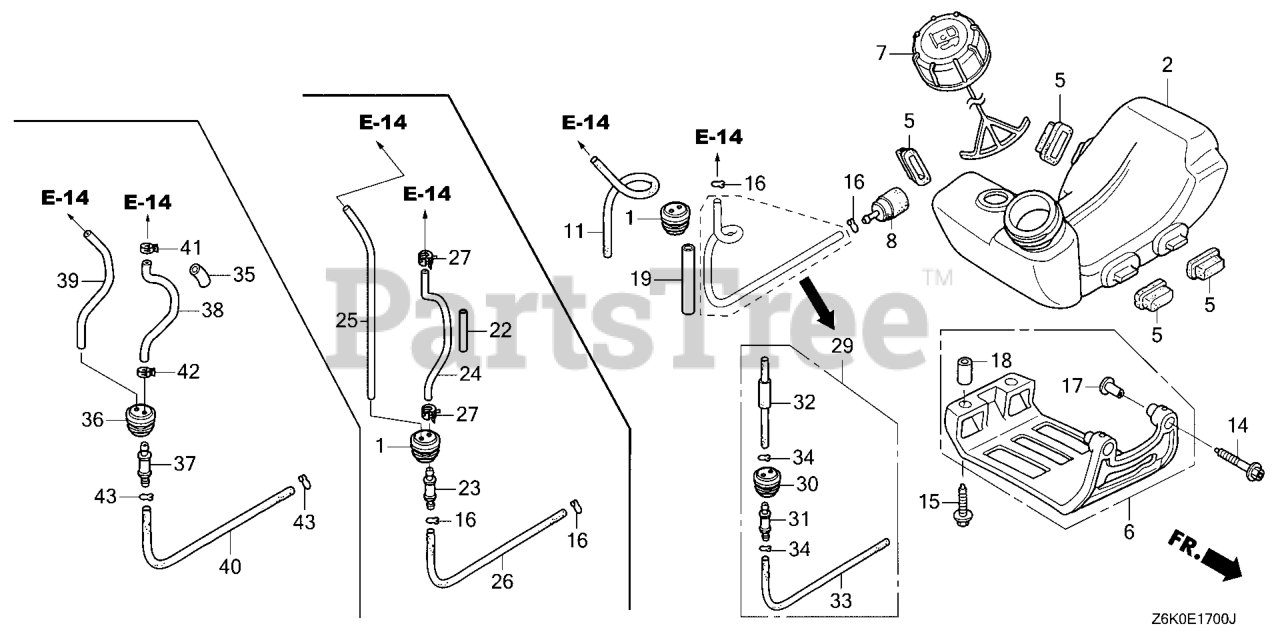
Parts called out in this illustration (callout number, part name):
2	TANK, FUEL
5	RUBBER, TANK MOUNTING
7	CAP ASSY., FUEL TANK
8	FILTER, FUEL
35	PROTECTOR, TUBE
36	GROMMET, FUEL TUBE
37	JOINT, FUEL TANK
38	TUBE, FUEL
39	TUBE, FUEL RETURN
40	TUBE A, FUEL
41	CLAMP, TUBE
42	CLAMP, TUBE
43	CLIP, TUBE (B1 5)
